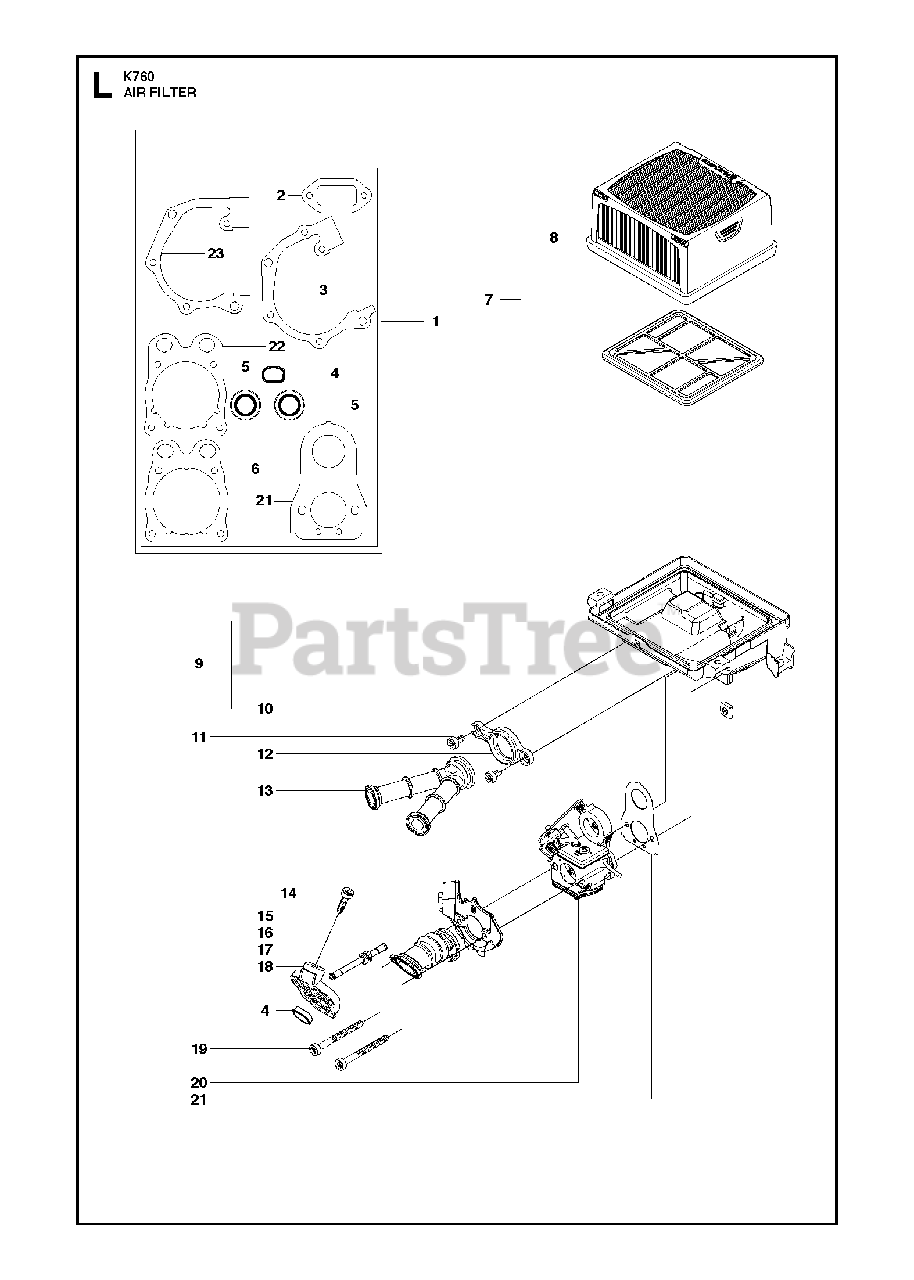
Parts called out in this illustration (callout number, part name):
1	GASKET KITincl. 2 - 6, 21 - 23
2	GASKET
5	SEALING RINGBlue
7	AIR FILTER ASSYIncl. 8
8	AIR FILTER ASSY
9	CARBURETTOR BRACKETIncl. 10
11	SCREW ITXSCM
12	FLANGE INLET PIPE
14	SCREW ITXSCM
17	IMPULSE HOSE
18	PLATE
19	SCREW ITXSCM
20	CARBURETTORZama C3-EL53
